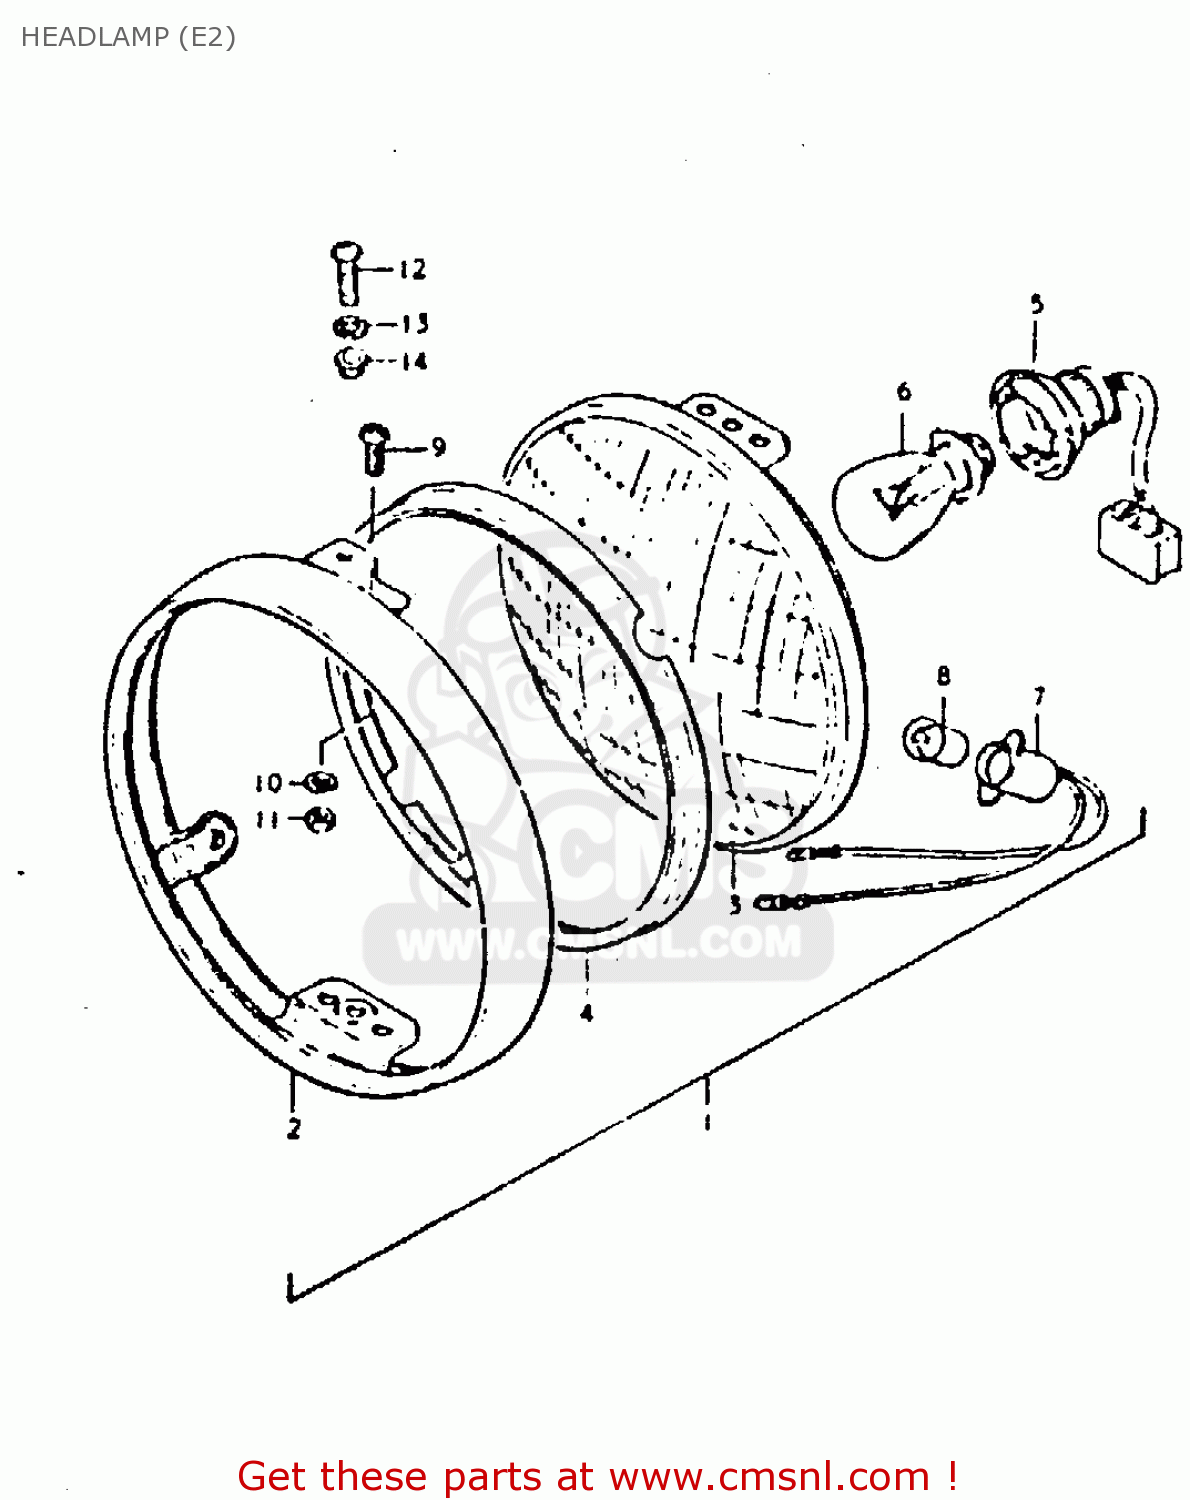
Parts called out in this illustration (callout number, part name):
1	HEADLAMP ASSY
2	RIM
3	UNIT, HEAD LIGHT
4	RETAINER,HEADLAMP
5	SOCKET
6	BULB 12V35/35W
7	SOCKET
8	BULB(12V3.4W,STANLEY,A72A)
9	SCREW
10	LOCK WASHER
11	NUT
12	SCREW
13	WASHER,LOCK
14	WASHER
